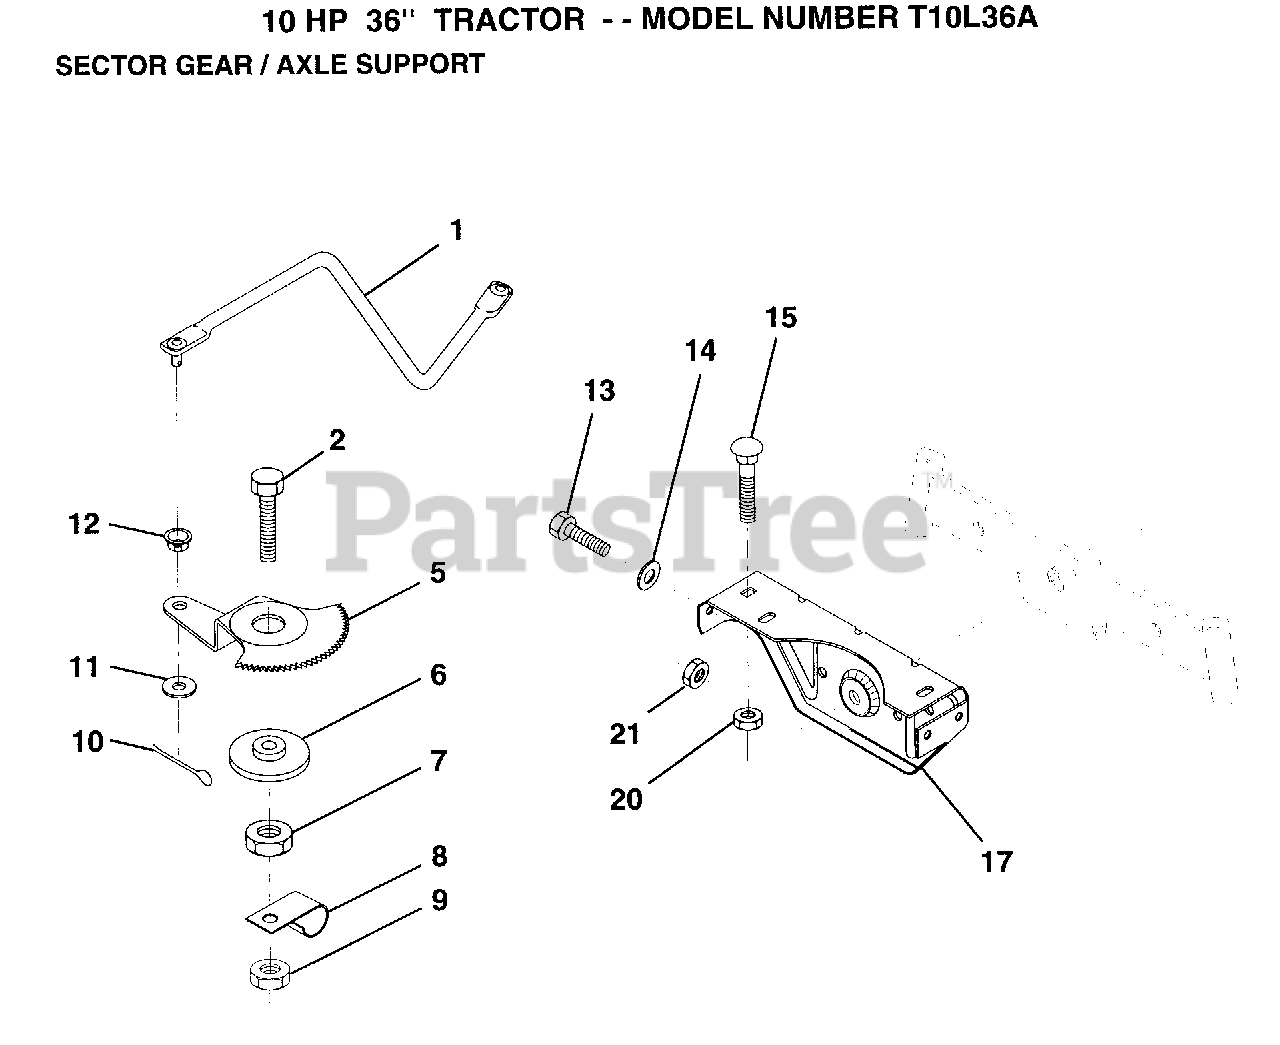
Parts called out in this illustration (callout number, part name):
1	DRAG LINK
2	"BOLT,HEX"
5	GEAR SECTOR
6	BUSHING
7	NUT
8	CLIP INSULATOR
9	NUT LTV
10	COTTER PIN
11	WASHER
12	BUSHING.DRAGLINK
13	BOLT
14	WASHER
15	BOLT
17	SUPT AXLE FRONT
20	NUT
21	NUT
